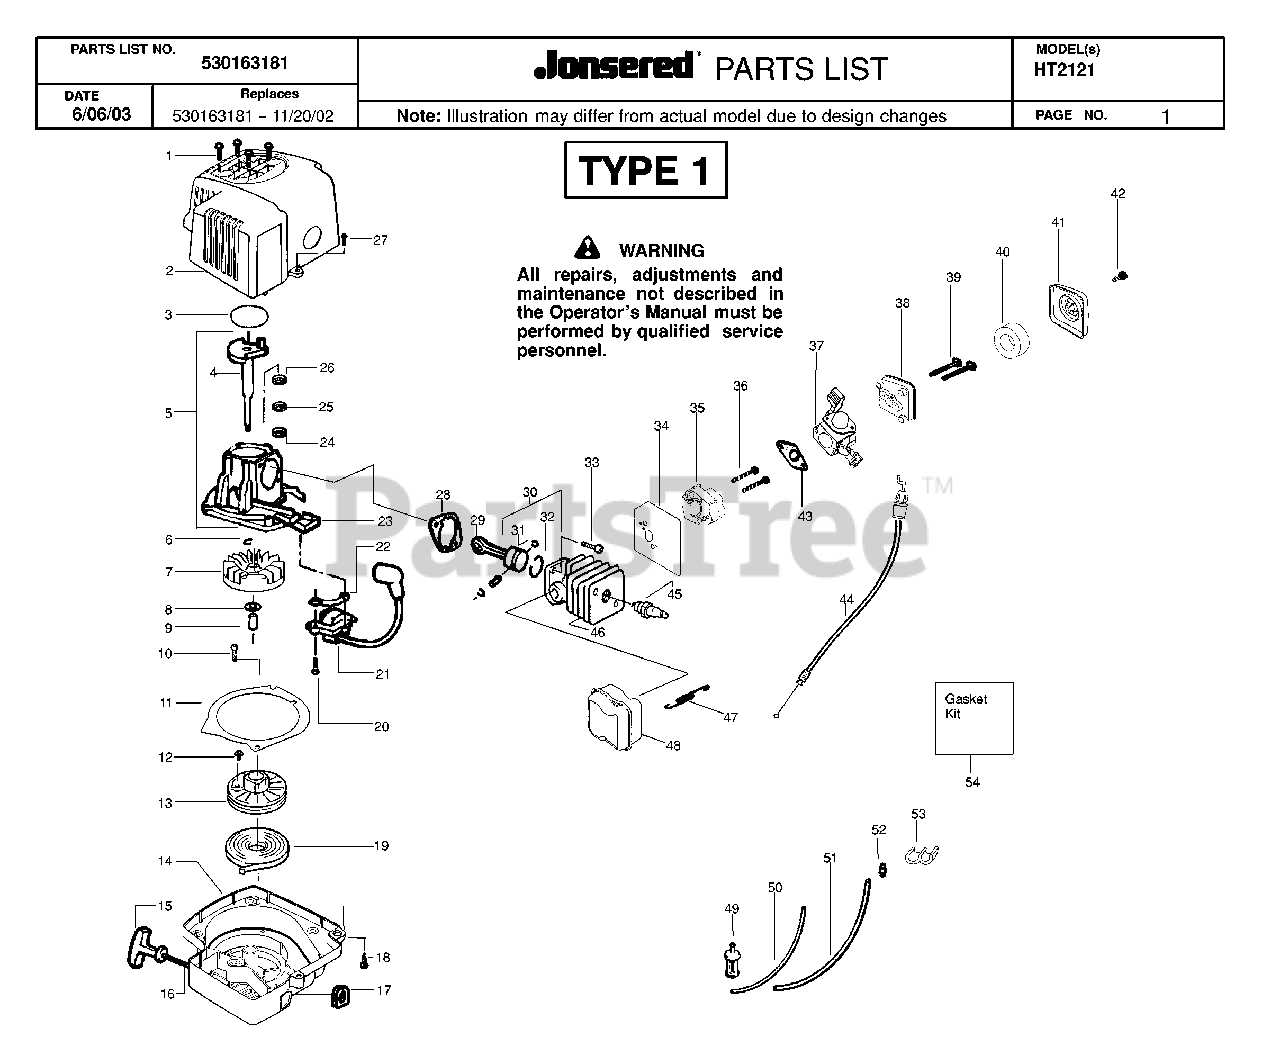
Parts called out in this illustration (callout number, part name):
2	ASSY-SHROUD
3	GASKET KIT
4	CRANKSHAFT
5	CRANK CASE/SHAFT ASSY.
6	RETAINING RING
7	FLYWHEEL
8	WASHER FLAT
10	SCREW-10-16 X 1/2 HI-LO
11	PLATE-BAFFLE
13	STARTER PULLEY
14	FAN HOUSING
15	HANDLE-STARTER
19	STARTER SPRING
21	IGNITION MODULE
22	SPACER - IGNITION MODULE
23	CRANKCASE
24	OUTER BEARING
26	BEARING
28	GASKET KIT
30	PISTON
31	WRIST PIN RET.
32	PISTON RING
34	GASKET KIT
35	ADAPTER-CARBURETOR
36	SCREW - CARB. ADAPTOR
41	AIR FILTER COVER
43	GASKET KIT
44	ASSY-THROTTLE CABLE
45	PLUG-SPARK (RCJ-6Y)
46	KIT-CYLINDER
48	KIT-SPARK MUFFLER
49	ASSY-PICK-UP
52	FUEL LINE FITTING
54	GASKET KIT
530071601	CARBURETOR
530071633	CARBURETOR ASSY (C1U-W13A)
